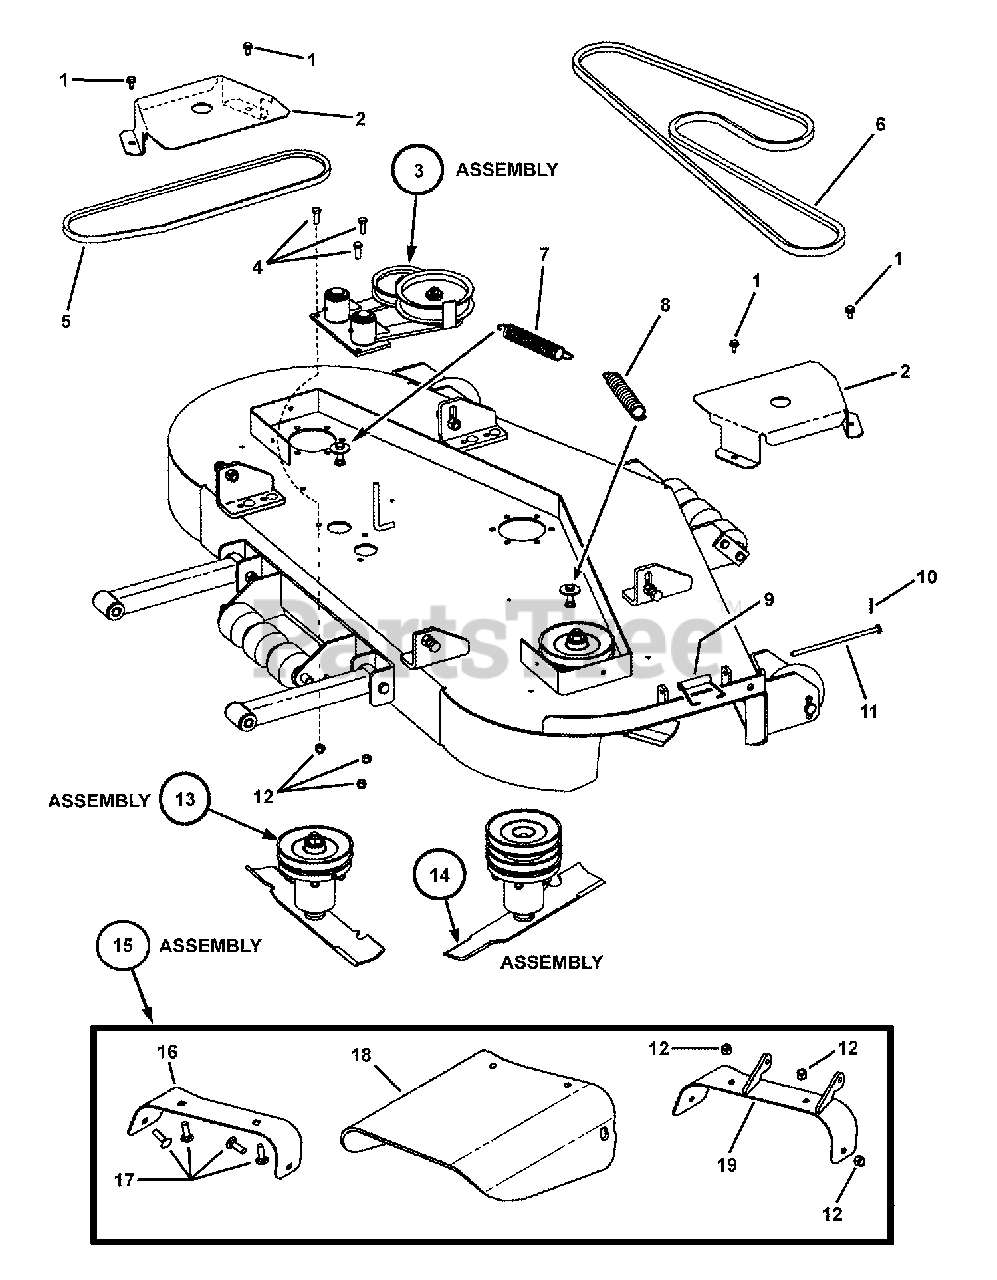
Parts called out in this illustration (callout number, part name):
1	SCREW, 5/16-18 x 5/8" Hex Washer Self-Tap
2	BELT COVER, 61" Deck
4	SCREW, 3/8-16 x 1" Hex Head Cap, GR 5
5	*BELT, Primary (HB Section, 94.2" effective length)
6	*V-BELT, Secondary- 61" (HB Section, 127.0" effective length)
7	SPRING, Idler (1.17" O.D. x 7.5" long)
8	SPRING, Idler Primary (1.25" O.D. x 10" long)
9	SPRING, Chute
10	PIN, 3/32 x 1" Cotter
11	PIN, Chute Hinge
12	NUT, 3/8-16 Hex Nyloc
16	DEFLECTOR BOTTOM (61" Deck)
17	BOLT, 3/8-16 x 1-1/4" Square Neck Carriage, GR 5
18	CHUTE, Rubber (61" Deck)
19	WELDMENT, 61" Discharge Chute
